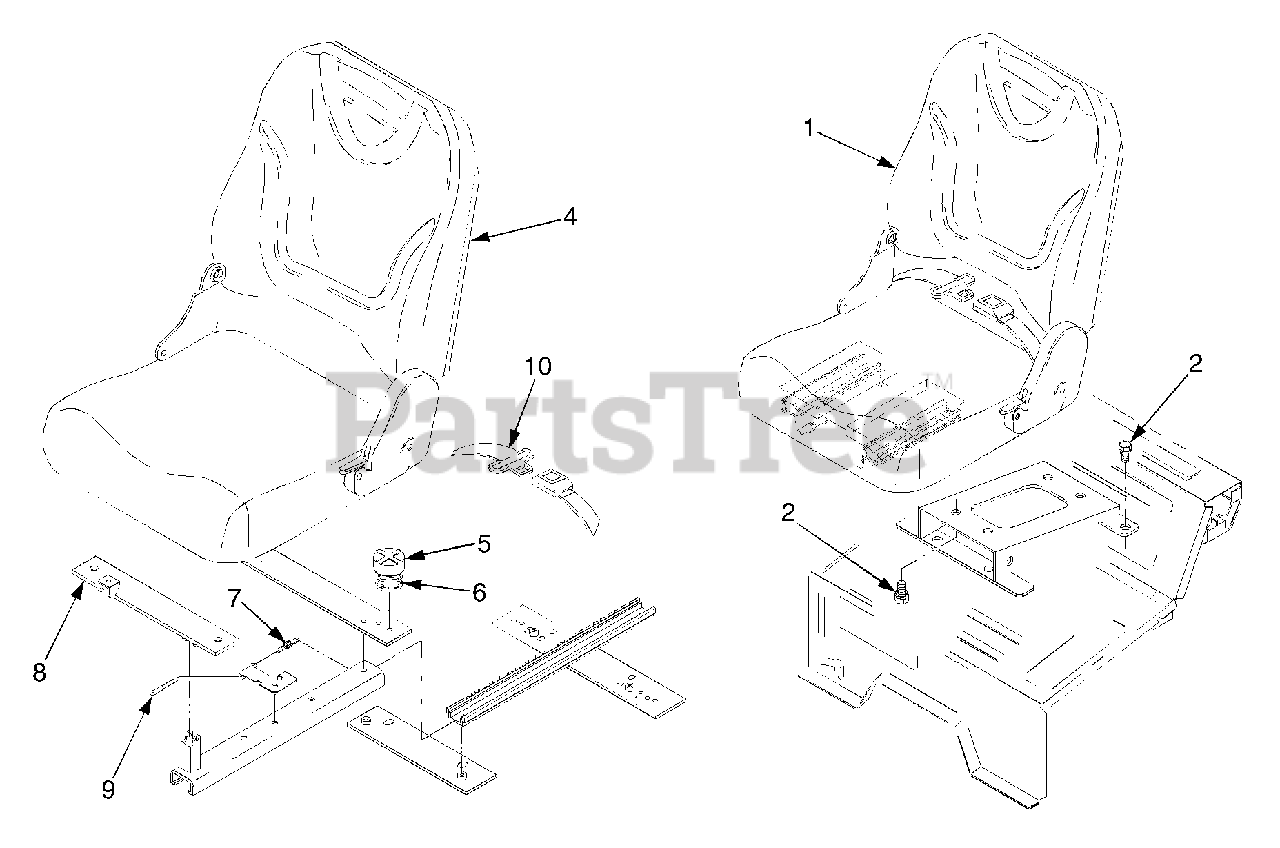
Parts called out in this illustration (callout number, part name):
1	Seat Ass'y
5	Rubber, Damper
6	Spring, Damper
